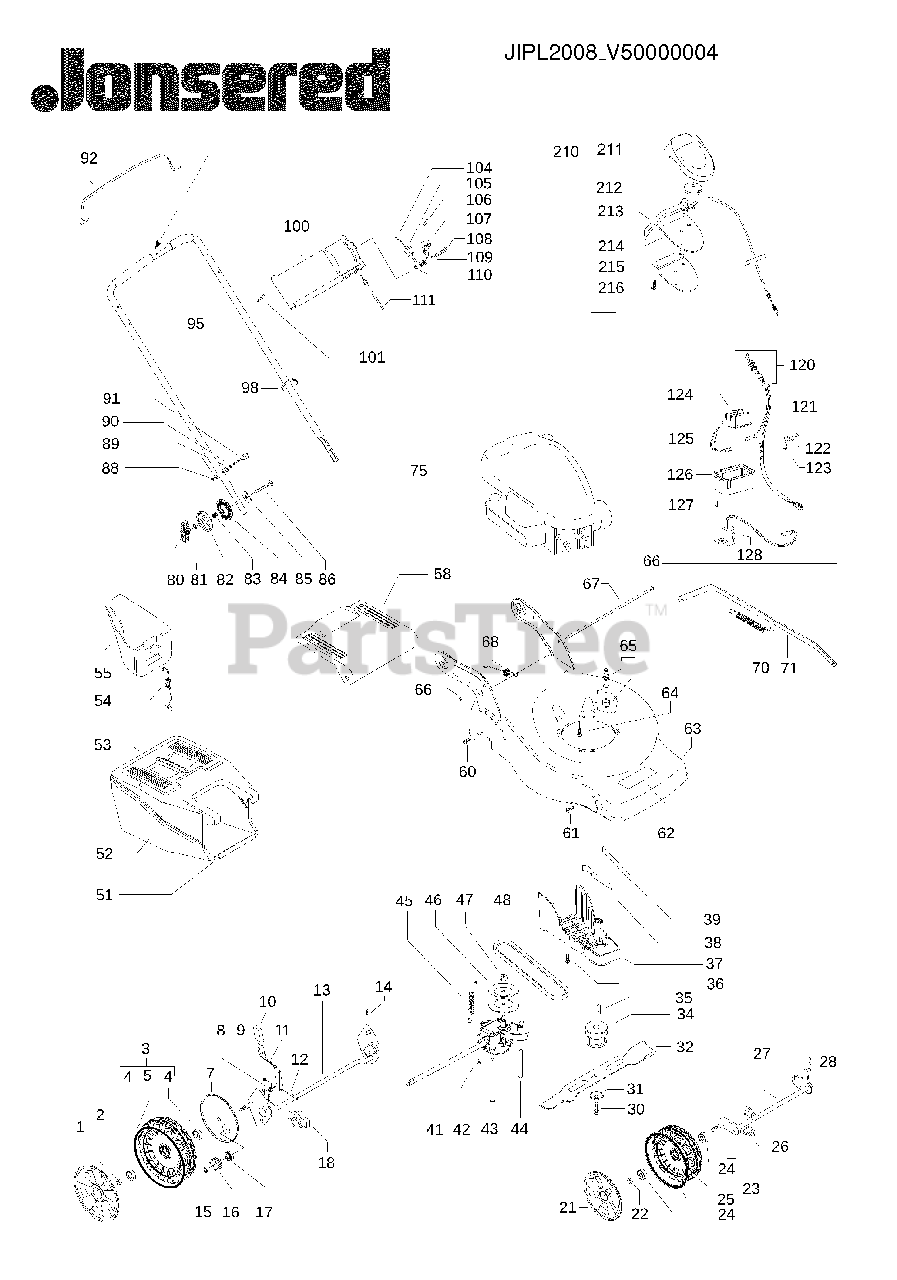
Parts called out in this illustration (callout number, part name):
211	COVER, DRIVE CONTROL, TOP
212	PULLEY, DRIVE CONTROL
213	LEVER, DRIVE CONTROL
214	COVER, DRIVE CONTROL BOTTOM
215	BRACKET, DRIVE CONTROL
216	SCREW, PHILLIPS HEAD 10 X 5/8
